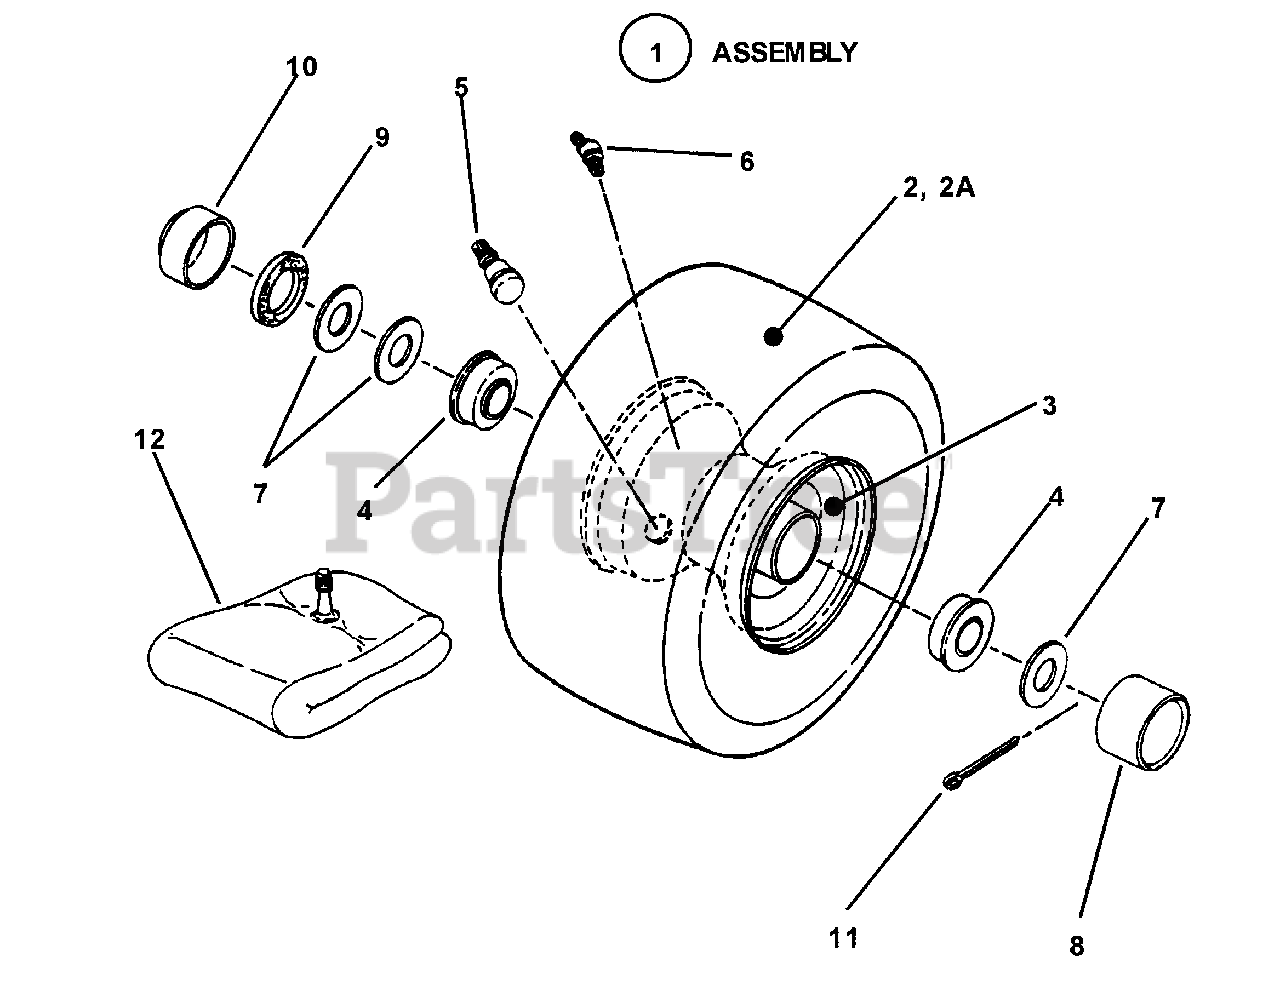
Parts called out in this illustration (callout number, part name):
1	ASSEMBLY, Tire & Rim
2	TIRE, 4.10/3.50 x 4
2A	TIRE 11.00/4:00 x 4
3	RIM
4	BEARING, Ball
5	VALVE, Air (Snap-in)
6	FITTING Lube
7	WASHER, 3/4" I.D.
8	CAP, Hub
9	SEAL, Felt
10	CAP, Dust
11	PIN, Cotter 5/32 x 1"
12	TUBE, Inner
